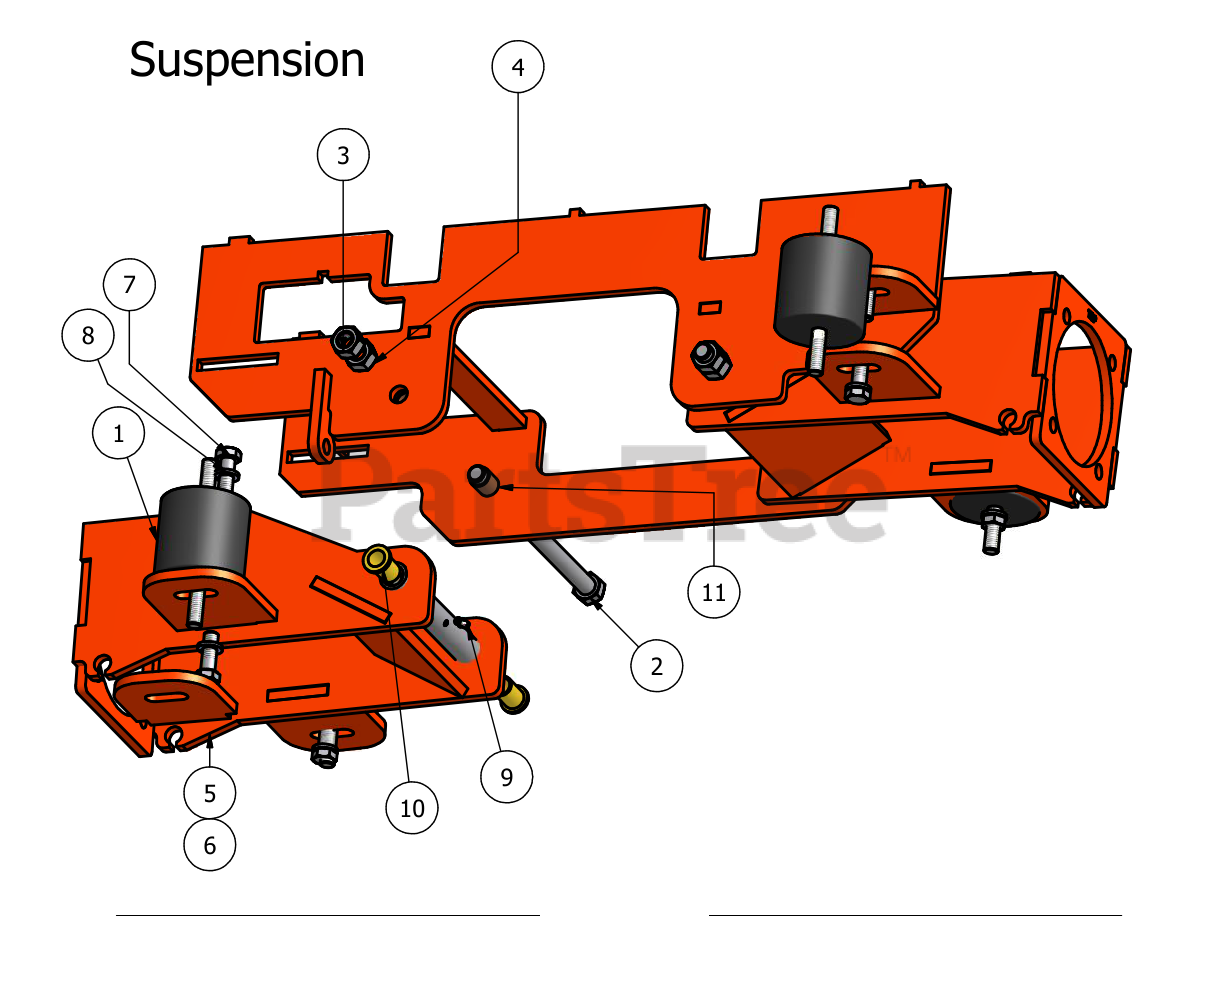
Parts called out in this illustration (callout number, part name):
1	Vibration Mount
2	5/8" x 10" Hex Bolt (Grade 8)
3	5/8" Nylock 1/2 Jam
5	60" Inner Suspension Cage
6	72" Inner Suspension Cage
7	1/2" x 1" Hex Bolt
8	1/2" Lock Washer
9	Grease Fittting (Drive-In)
10	Shoulder Spacer
11	3/4" Brass Bushing
